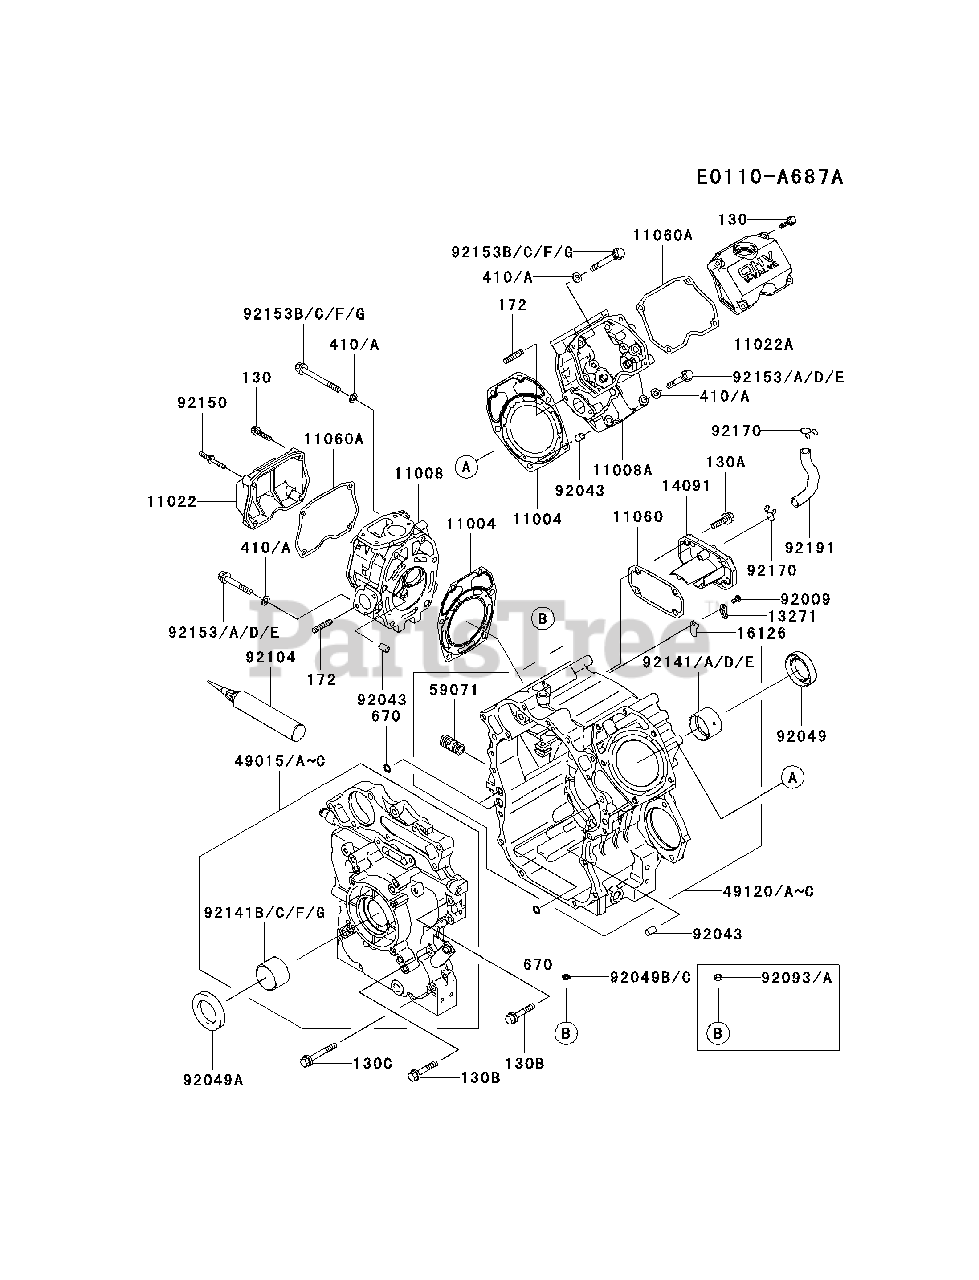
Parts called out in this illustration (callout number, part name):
130	BOLT-FLANGED,6X30
130A	BOLT-FLANGED,8X30
130B	BOLT-FLANGED,8X45
130C	BOLT-FLANGED,8X60
172	BOLT-STUD,8X22
410	W-PLAIN-S,8MM
670	O RING,11MM
92191	TUBE
